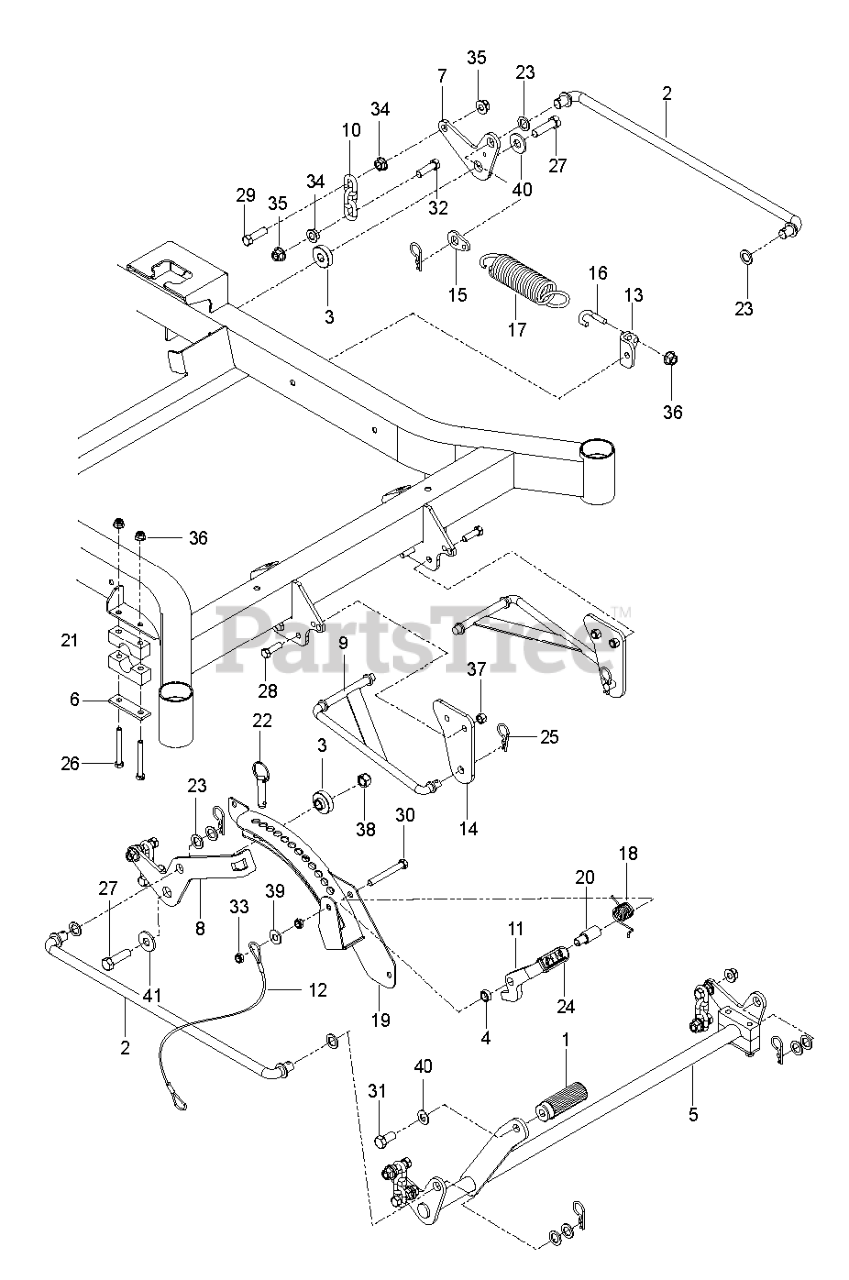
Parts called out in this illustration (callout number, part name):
1	PEDAL, DECK HEIGHT
2	CROSS LINK
3	SPACER.IDLER.METAL.POWDER
4	SPACER, .3
5	LIFT.PNT.MZ.DECK.WELD.E-DIP
6	REINFORCEMENT.PLATEX431
7	BELLCRANK, RR, LIFT
8	BELLCRANK, RR, RT
9	STRUT LINKAGE
10	LIFT CHAIN - 3 LINK
11	LATCH, TRANSPORT
13	MOUNT, SPRING
14	MOUNT, STRUT
15	TAB, SPRING
18	SPRING, TORSION
19	HEIGHT, ADJUST, DECK
20	PIVOT, LATCH, TRANSPORT
21	PILLOW BLOCK
22	PIN, 1/2 X 1 1/2, DETENT RING
24	GRIP, TRANSPORT-RELEASE
25	PIN, COTTER 1 3/4
26	HCS 5/16C X 2-3/4
27	HCS 1/2-13 X 1 3/4 GR 8
28	BOLT 5/16-18 X 3/4
29	HCS 7/16C X 1 1/2
30	BOLT.HEX.FIN.3/8-16 X 3.GR5
31	HHCS 1/2-13 X 1
32	HCS 7/16 - 14 X 1 3/4
33	NUT HEX 3/8-16 NYLON, THIN
34	NUT 7/16-14 HEX WHIZ LK
35	NUT 7/16C WHIZ
36	5/16-18 NYLOC FLANGE NUT
37	NUT 3/8-16 NYLOC
38	NUT 1/2-13 HEX NYLOC ZD
39	WASHER 3/8 FLAT
40	CONTACT BELLSPR 1/2
41	WASH USS FLAT 1/2
